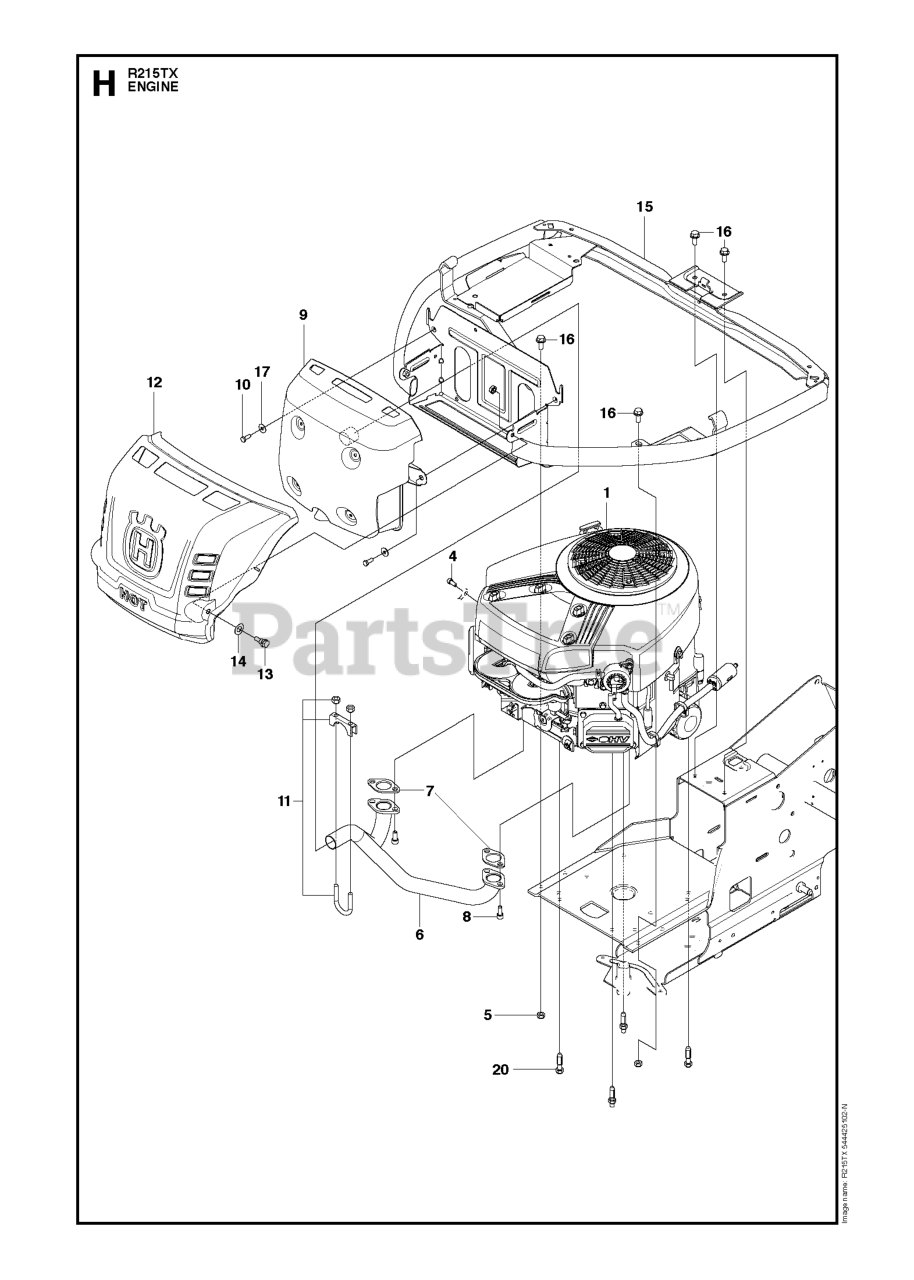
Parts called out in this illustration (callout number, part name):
5	LOCKNUT M8
11	CLAMP
12	RP HEAT SHIELD
14	SPRINGWASHER
15	ENGINE FRAME
17	WASHER - 26X6.5X1.6
20	STUD SCREW
